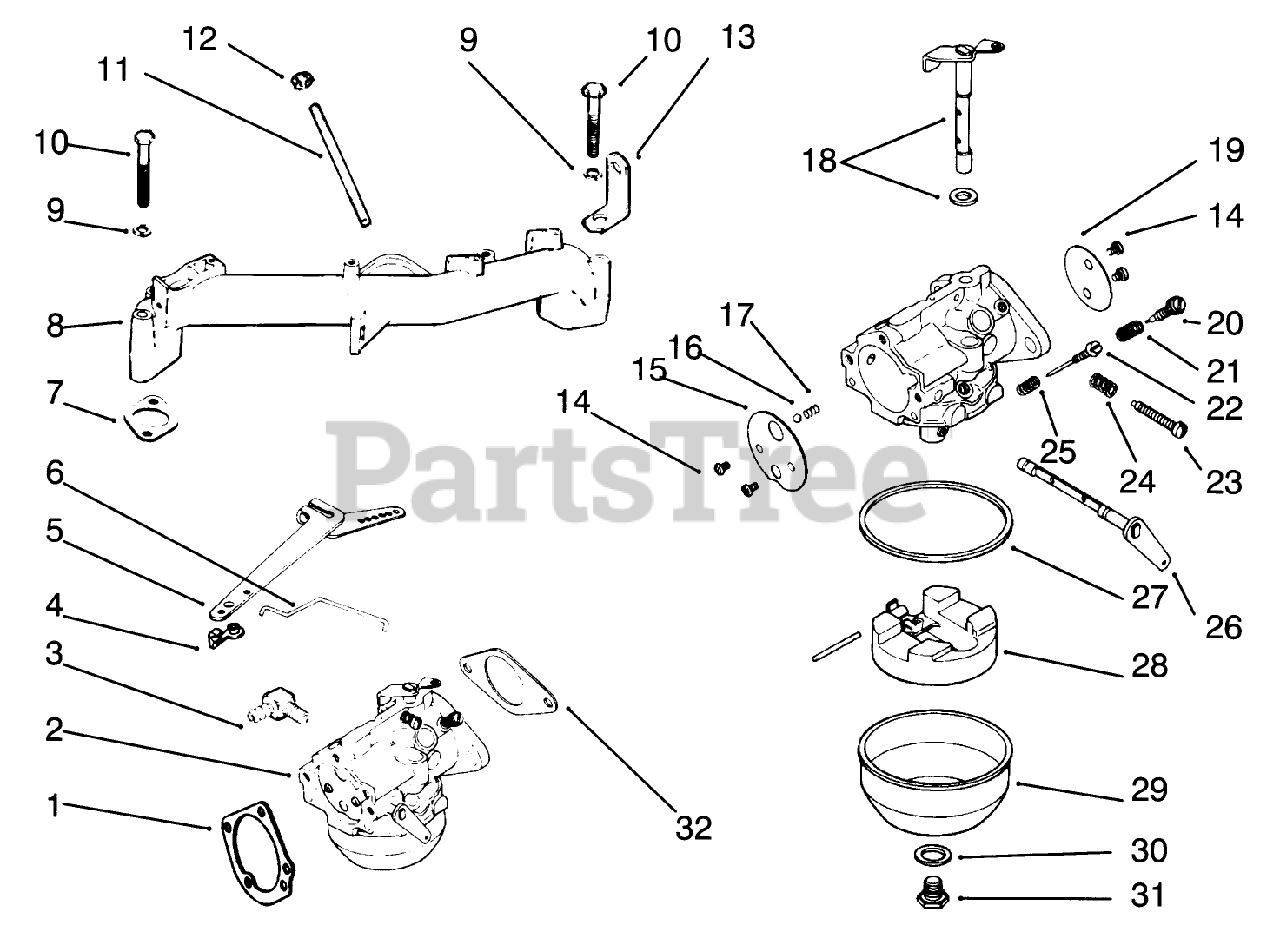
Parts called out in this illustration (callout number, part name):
1	Gasket
2	Carburetor
3	Connector-90deg.
4	Bushing
5	Arm-Governor
6	Kit-Governor Linkage (Incl. Ref. #13)
7	Gasket-Intake
8	Manifold-Intake
9	Washer
10	Screw-H.C.
11	Stud
12	Nut
13	Strap-Lifting
14	Screw-Throttle Plate
15	Plate-Choke
16	Ball-Choke
17	Spring-Choke
18	Shaft-Throttle Lever & Sea
19	Plate-Throttle
20	Valve-Needle
22	Needle-Main Fuel
26	Lever-Choke
27	Bowl-Gasket
28	Float Kit-(Incl. Pin)
30	Gasket-Bowl
31	Screw-Bowl
32	Gasket
